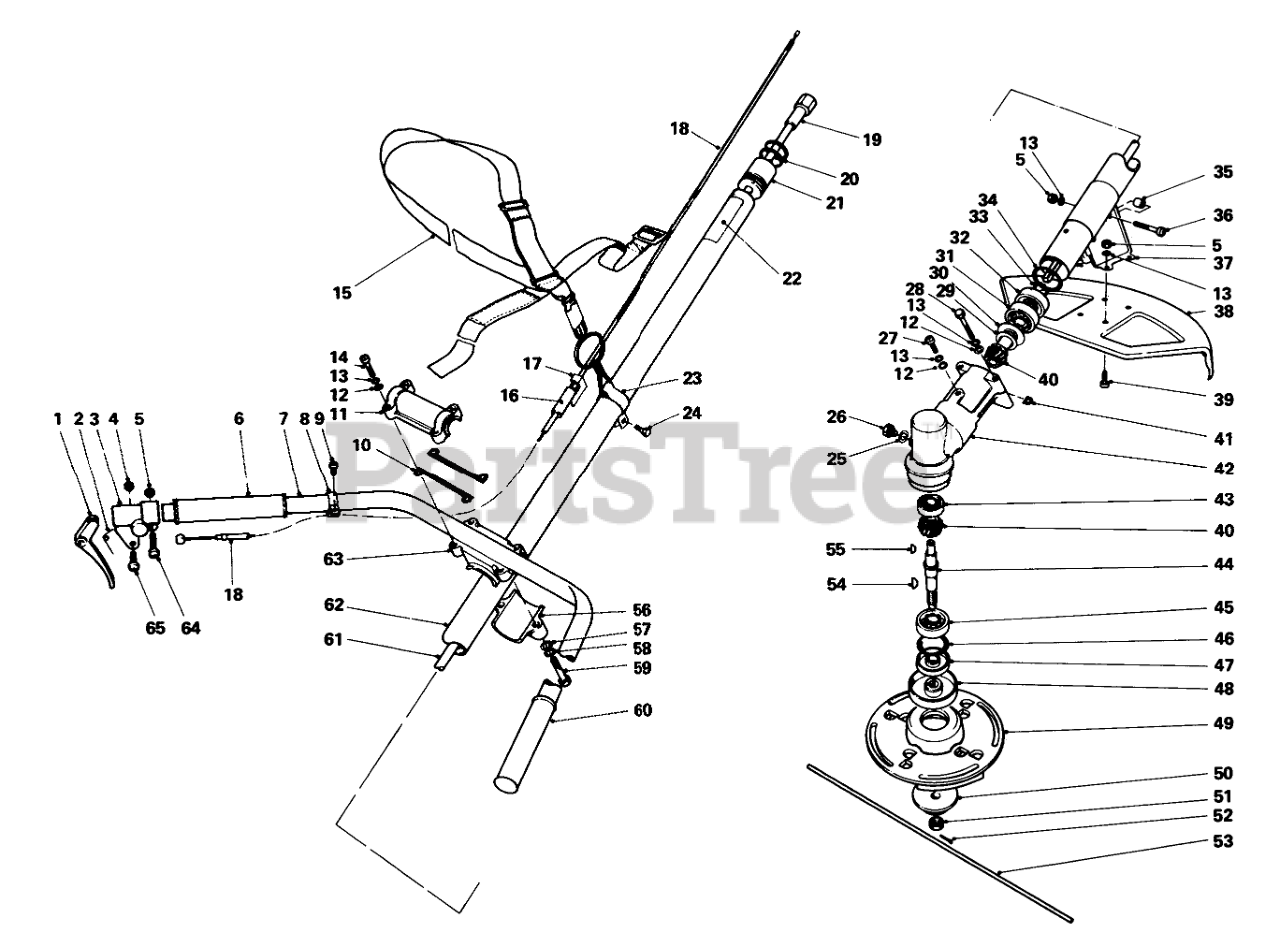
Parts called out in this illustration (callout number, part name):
1	Throttle Trigger
2	Return Spring
3	Bracket, Throttle Trigger
5	Nut
6	Right Hand Grip
7	U-Handle
9	Screw
10	Spacer
11	Handle Bracket, Upper
12	WASHER
13	Washer
15	Shoulder Belt
17	Clamp
18	THROTTLE CABLE
19	Coupler
20	O-Ring
21	Bushing
22	Decal, Caution
23	Swivel Hook
25	Gasket
27	SCREW
29	Washer
30	Washer
31	Ball Bearing
32	Ball Bearing
33	Circlip
34	Circlip
35	Spacer
36	Screw
37	Bracket-Head Guard
38	Shield
39	SCREW
40	Gear Set
41	Spacer
42	Gear Housing
43	Ball Bearing
44	Shaft-PTO
45	Ball Bearing
46	Circlip
47	Oilseal
48	Plate-Blade Fixing
49	Cutter Head
50	WASHER
52	Cotter Pin
53	Cotter Pin
54	Woodruff Key
55	Woodruff Key
56	Handle Bracket, Lower
57	Washer
58	Washer
60	LH GRIP
61	Drive Shaft
62	Housing, Driving Shaft
63	Body, Handle Bracket
65	Screw
